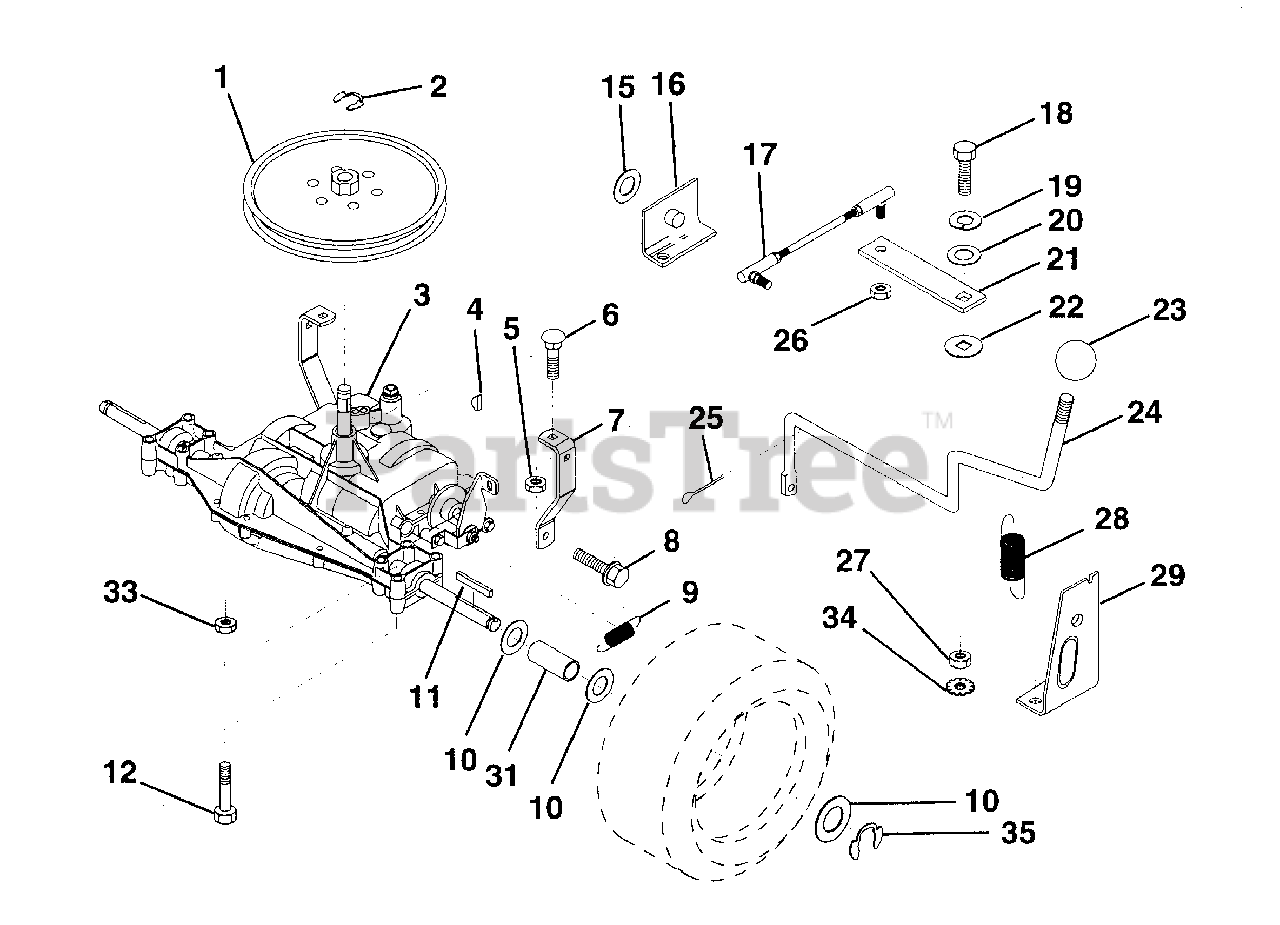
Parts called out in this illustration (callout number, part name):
2	Ring, Retainer
4	Key, Woodruff #9
5	Nut, Crownlock 5/16-18
6	Bolt, Carriage 5/16-18 UNC x 3/4
7	Strap, Torque
8	Screw 5/16-18 x 3/4
9	Spring, Brake
10	Washer 25/32 x 1-1/4 x 16 Ga.
11	Key, Square
12	Bolt, Fin Hex 3/8-16 Unc x 2-3/4
15	Washer 17/32 x 1 x 16 Ga.
16	Support Handle Shift LH
17	Link, Shift
18	Bolt, Fin Hex 1/4-28 UNF x 3/4 Gr. 8
19	Washer, Lock 1/4
20	Washer 9/32 x 3/4 x 10 Ga.
21	Arm, Shift
22	Washer, Shift Plate
23	Knob, Rd 1/2-13
25	Pin, Cotter 1/8 x 1
26	Locknut 5/16-24 UNF
27	Nut, Keps 5/16-18
28	Extension, Spring
29	Support Handle Shift RH
31	Spacer Axle
33	Nut Crownlock 3/8-16 Unc
34	Washer External Tooth 5/16
